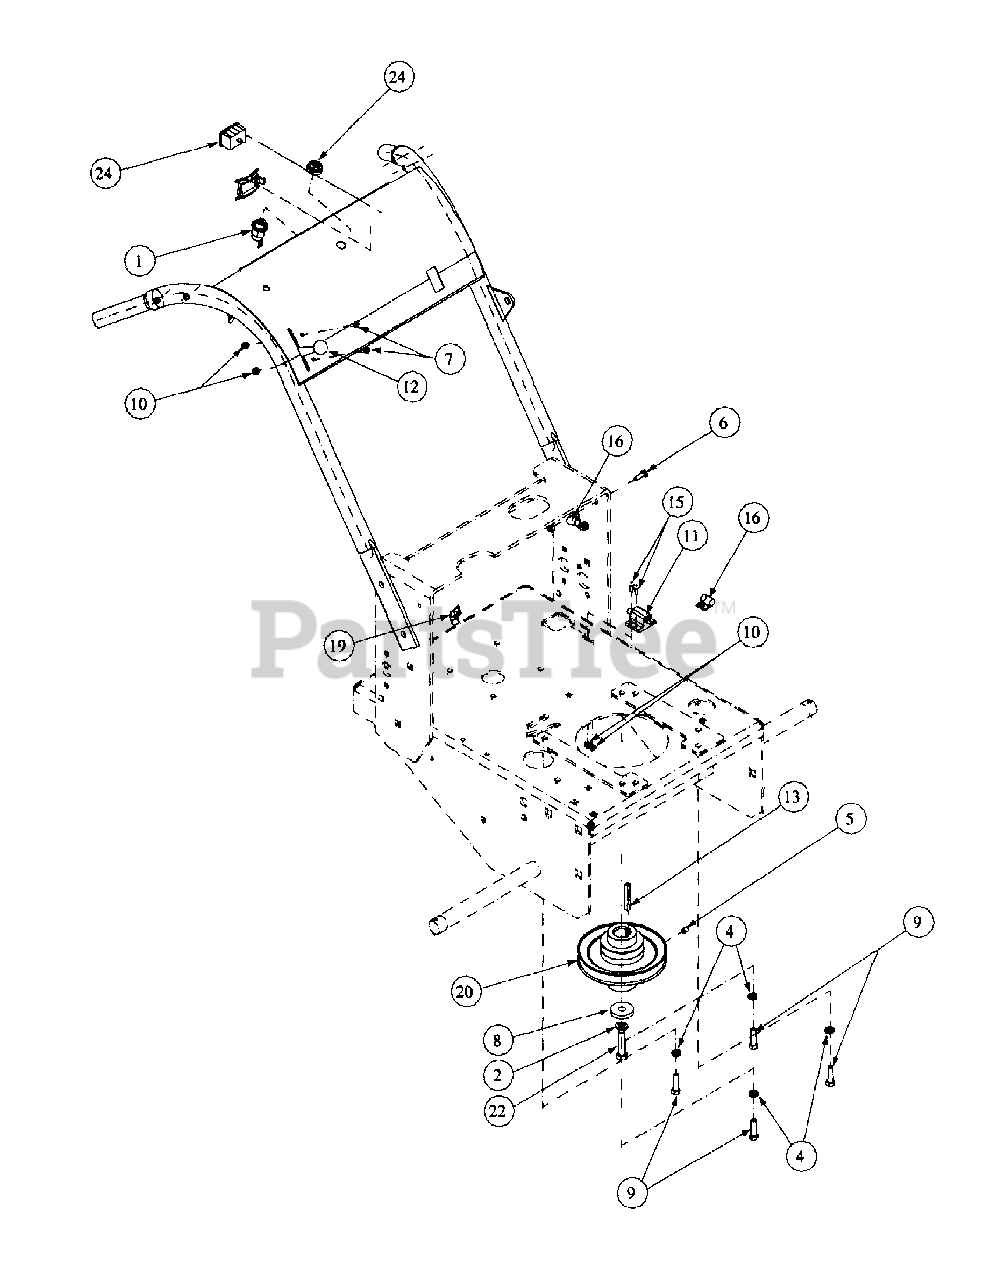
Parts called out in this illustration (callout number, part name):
1	Single Ignition ON/OFF Switch
2	Lock Washer, M10 Zinc
3	Lock Nut, Nylon Insert, 1/4-20
4	Lock Washer, 5/16
5	Nylock Screw, 5/16-18 x 3/8
6	Hex Cap Screw, 1/4-20, .75
7	Screw, Hex Washer, 10-32 x 1/2
8	Clutch Washer
9	Cap Screw, 1.25 x 30
10	Lock Nut, Nylon Insert, 10-32
11	Delta Switch
12	Control Throttle w/Detent, 39.2
13	Key Stick, 1/4 x 1/4 x 2
14	Harness Wire
15	Machine Screw, 10-32 x 5/8
16	Support Clamp Tubing, 1/2"
17	Nut, w/Cap, 5/8-32, Ignition
18	Engine, 14HP Kawasaki
19	Support Clamp, 3/8 OD
20	Double Pulley Gear
21	Belt
22	Capscrew, M10-1.5 x 50 mm
24	Hour Meter
25	Harness Hourmeter
